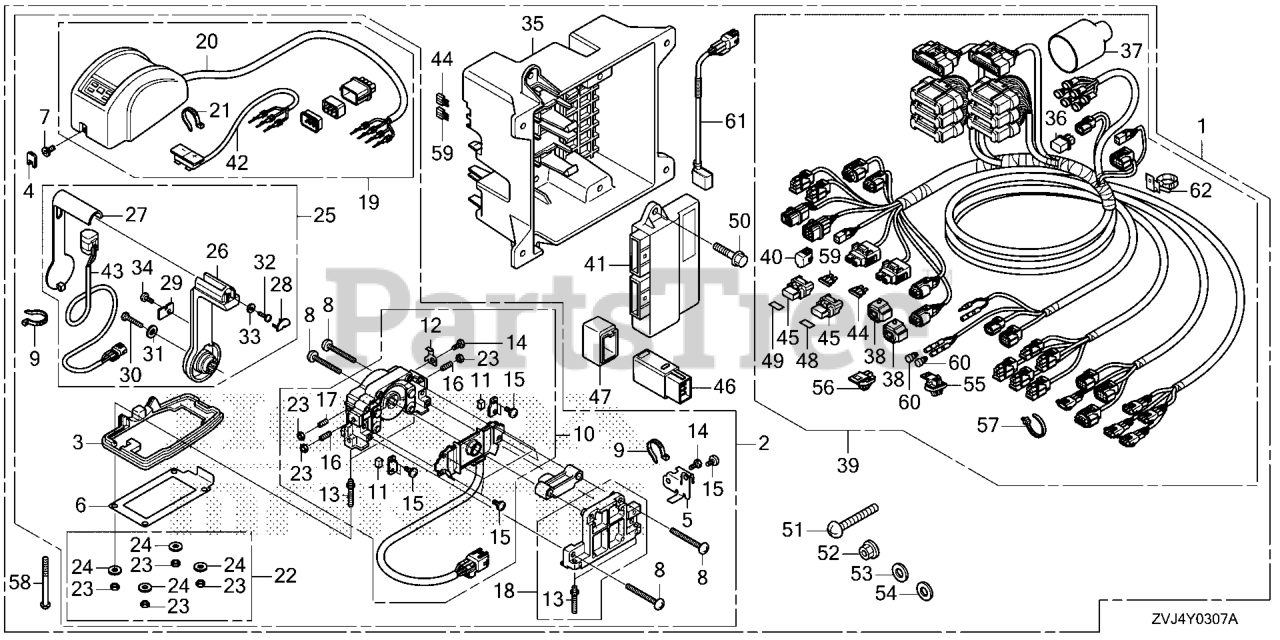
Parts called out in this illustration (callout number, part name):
1	BOX KIT, REMOTE CONTROL (TOP MOUNT SINGLE)(MAIN)
1	BOX KIT, R/C
2	BOX ASSY., REMOTE CONTROL (TOP MOUNT SINGLE)(RH)
3	GASKET (SINGLE)
4	COVER, CAP
5	PLATE, COVER FIX (SINGLE)
6	SHEET, WATERPROOF (SINGLE)
7	BOLT, SOCKET
8	SCREW
9	BAND, NYLON
10	HOUSING ASSY., L.
11	SHOE, BRAKE
12	PLATE, HARNESS
13	BOLT, STUD
14	BOLT
15	SCREW
16	SCREW SET
17	SCREW SET
18	HOUSING ASSY., SINGLE
19	COVER ASSY., SINGLE
20	LED ASSY., COVER (S)
21	BAND, NYLON
22	NUT SET, MOUNTING
23	NUT
24	WASHER
25	LEVER ASSY., L.
26	LEVER
27	PANEL, LEVER (POWER TRIM-TILT)
28	CAP, LEVER
29	PLATE, LEVER PANEL
30	BOLT
31	WASHER
32	SCREW
33	WASHER
34	SCREW
35	CASE, CONTROL UNIT
36	TERMINATOR ASSY.
37	COVER, CONNECTOR (NOT AVAILABLE)
38	SUSPENSION, CONNECTOR
39	CABLE ASSY., REMOTE CONTROL (MAIN)
39	CABLE, REMOTE CONTL
40	CAP, DUMMY (WPC 4P 090 M) (RED)
41	UNIT ASSY., CONTL
42	SWITCH ASSY., SELECT
43	SWITCH ASSY., POWER TRIM-TILT
44	FUSE, BLADE (3A)
45	COVER ASSY., FUSE
46	RELAY ASSY., MAIN
47	SUSPENSION, RELAY
48	LABEL, FUSE (3A)
49	LABEL, FUSE (5A)
50	BOLT, FLANGE (6X20)
51	SCREW, PAN (5X40) DUAL QTY = (8) (SINGLE)
52	NUT, FLANGE (5MM)
53	WASHER, PLAIN (5MM)
54	WASHER, SPRING (5MM)
54	WASHER, SPG (5MM)
55	CLIP, CONNECTOR (DARK BLUE)
56	CLIP, CONNECTOR (DARK BROWN)
57	CLIP, HARNESS BAND (145MM) (BLACK)
58	SCREW, PAN (5X65)
59	FUSE, MINI (5A)
60	PLUG, CONNECTOR (INNER) (TROLLING CONTROL)
61	RELAY ASSY., CONTROL (NOT AVAILABLE)
62	HOLDER, CONNECTOR (128.6MM) (NATURAL)
